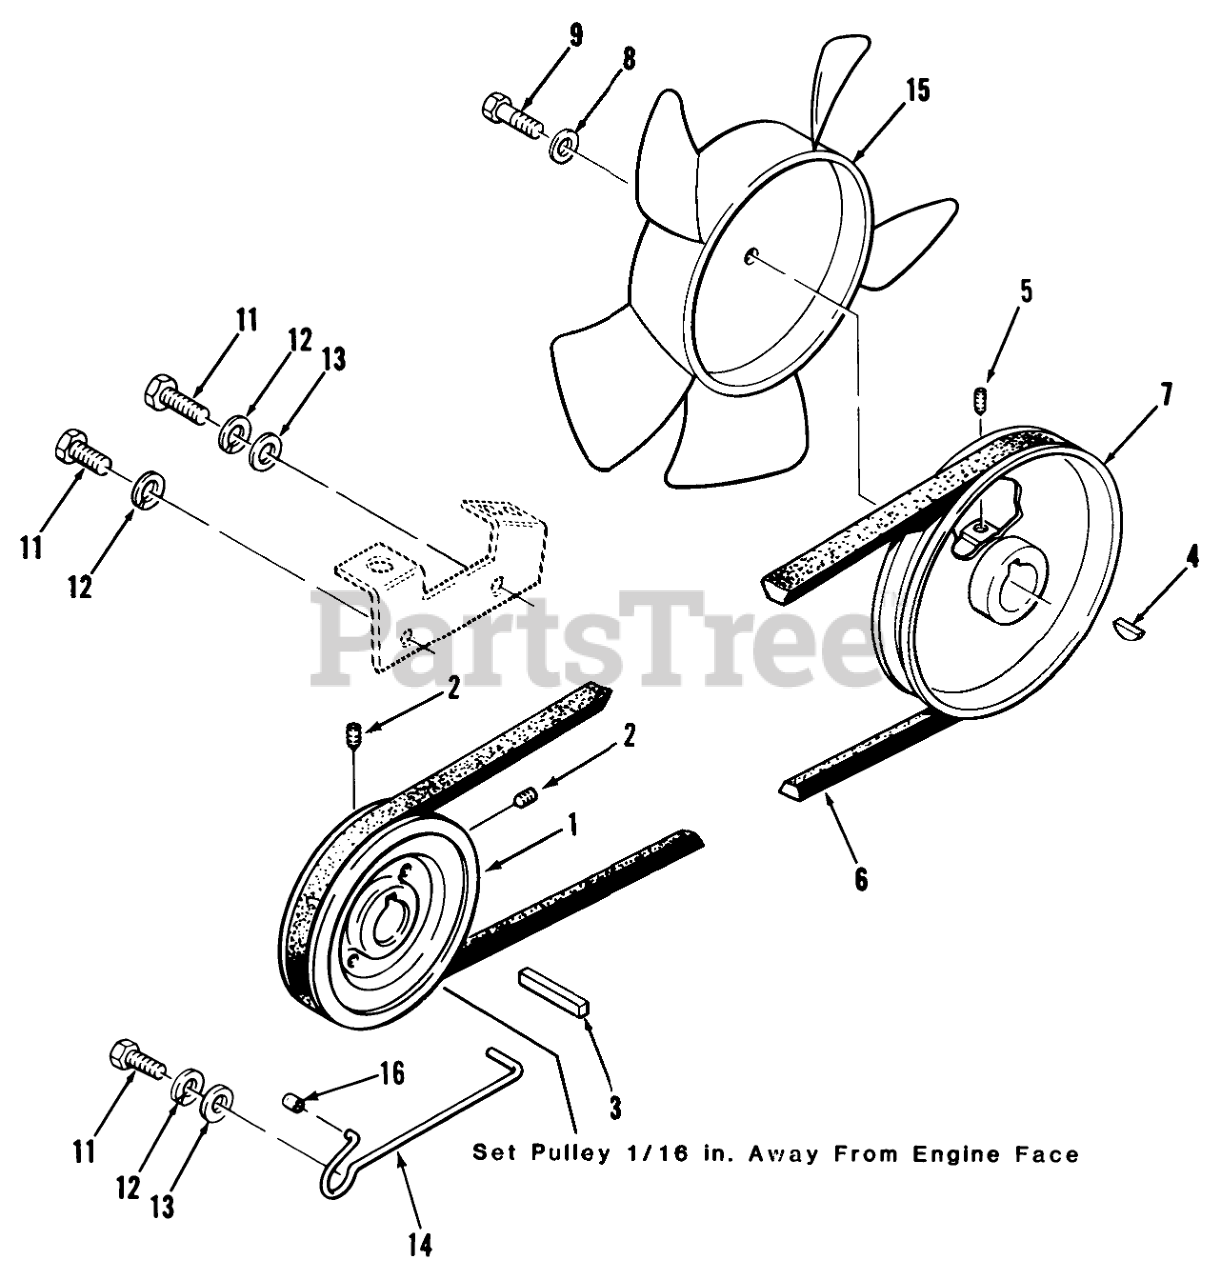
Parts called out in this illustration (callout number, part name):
1	PULLEY
2	Set Screw
4	KEY WOODR 1/8X1/2 DI
4	KEY-WOODRUFF
4	KEY-HI PRO
5	Set Screw
6	V-BELT TRANS DRIVE
6	V BELT
7	SHEAVE HYDRO INPUT
7	PULLEY
7	PULLEY-TRANSMISSION
8	WASHER
9	HEX HD CAP SCREW -4
9	H H C S
11	7/16-14 x 1 1/4 Bolt
11	Bolt
12	LOCKWASHER
13	WASHER
13	Washer
14	GUIDE BELT
14	Belt Guide-Bottom 308-8 Only
15	NYLON FAN-L-CW
